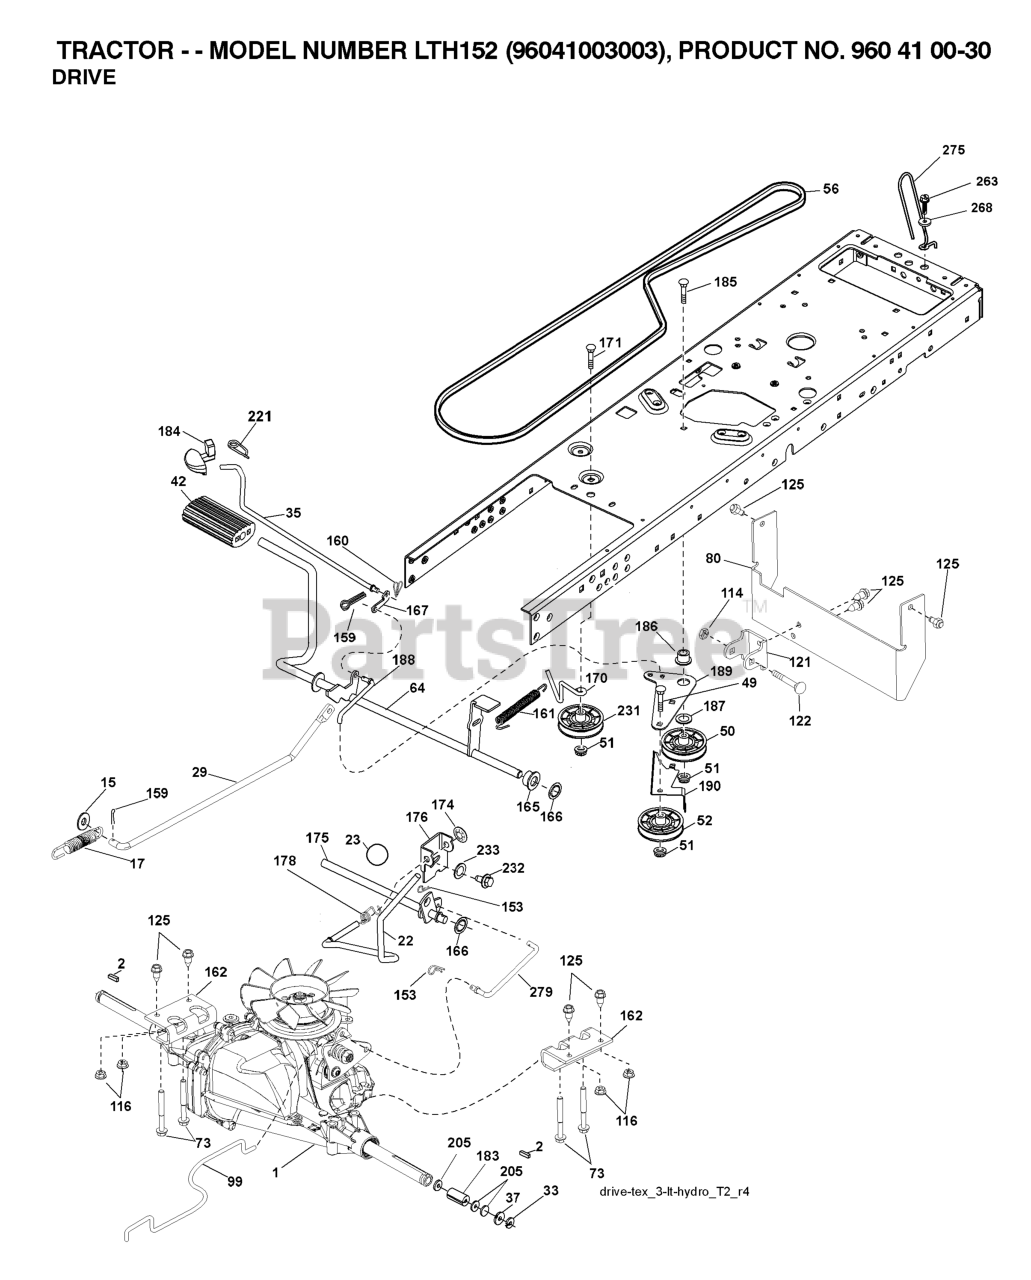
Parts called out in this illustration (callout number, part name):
2	SQUARE KEY
15	WASHER
17	SPRING.BRAKE.HG3000/3500
22	ROD.SHIFT.FENDER.TLT.2006
23	KNOB.DUCKHEAD.1/2
29	ROD.BRAKE.T2.TEX
35	ROD.CNTRL.PARK.PREDATOR.LT.TEX
42	PEDAL COVER T
50	IDLER.FLAT.910.OFFSET
51	NUT LOCK FLG 3/8-16 UNC
52	IDLER.V-GROOVE.910.OFFSET
64	SHAFT.ASM.PEDAL.BRAKE.
73	BOLT HEX 5/16-18 GR 5
80	RP.STRAP.TORQUE.FS.T2
99	ROD.ASM.BYPASS.SPRING.T2.FS
114	NUT.71038.31-18.HEX.NYLOCK
116	NUT LOCK HEX FLANGE 5/16-18
121	BRACKET STRAP TORQUE
122	BOLT.5/16-18X2.5
125	SCREW
153	RETAINER M
159	COTTER PIN
160	RETAINER CLIP
161	SPRING, RETURN LT
162	ADAPTER.TRANSAXLE.T2.TLT.DRWBR
165	BUSHING.SHAFT.BRAKE.HAND
166	NUT.PUSH.625.2006
167	LATCH.BRAKE.SPRING
170	KEEPER.CENTER SPAN.1.688
174	NUT.PUSH.500.2006
175	SHAFT.ASM.SHFT.T2.TLT
176	ARM.CLEVIS.ROD.SHIFT
178	SPRING.SHIFT.GT2006
183	SPACER, AXLE PVST
184	HANDLE PARKING BRAKE
186	SPACER.RETAINER
187	WASHER 12/32X2X10GA
188	RP.LINK.CLUTCH.GROUND.DRIVE
189	BELLCRANK.GROUND.DRIVE.TEX.
190	KEEPER.BELLCRANK.DRIVE
221	RETAINER.SPRING.CLIP.H
231	IDLER.V-GROOVE.1.688.OFFSET
232	BOLT FIN HEX 7/16-14 X 1
233	WASHER SERRATED
279	LINK SHIFT
